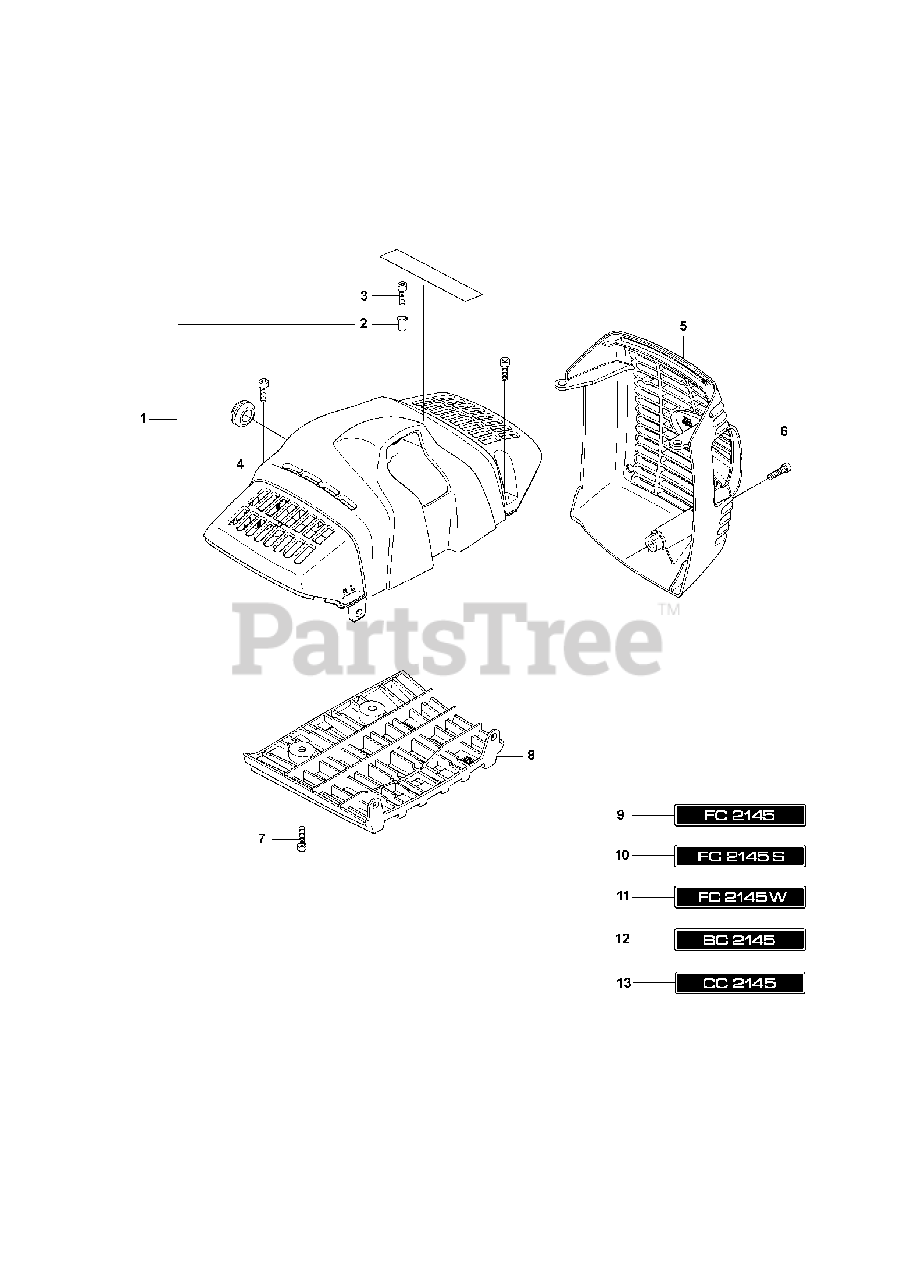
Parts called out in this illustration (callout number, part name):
3	SCREW IHSCFM
5	MUFFLER COVER
6	SCREW IHSCFM
7	SCREW IHSCFM
